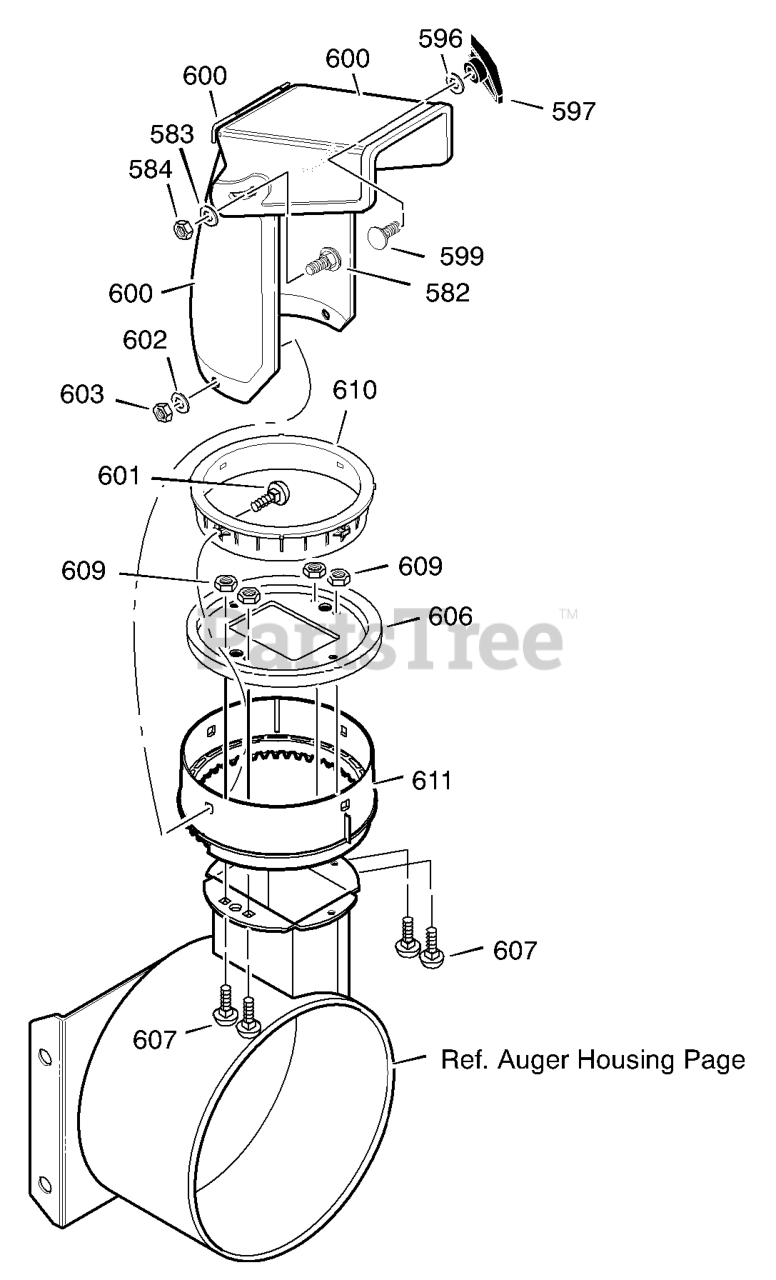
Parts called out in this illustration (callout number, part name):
582	BOLT, 5/16-18 X 1.00 CARR.
583	WASHER, FLAT
584	NUT, 5/16-18 NYLOCK
596	WASHER
597	KNOB, WING 3.00
598	NUT, 5/16-18 REGHEX
599	BOLT, 5/16-18 CARR. YZ
600	CHUTE ASSEMBLY
601	BOLT, 5/16-18 CARR.
602	WASHER, FLAT
603	NUT, 5/16-18 HEXNYL
606	CHUTE COLLAR
607	SCREW, 1/4-20 X 0.75
609	NUT, 1/4-20 HEX NYLOCK YZ
610	RETAINER RING INNER
611	RETAINER RING OUTER
